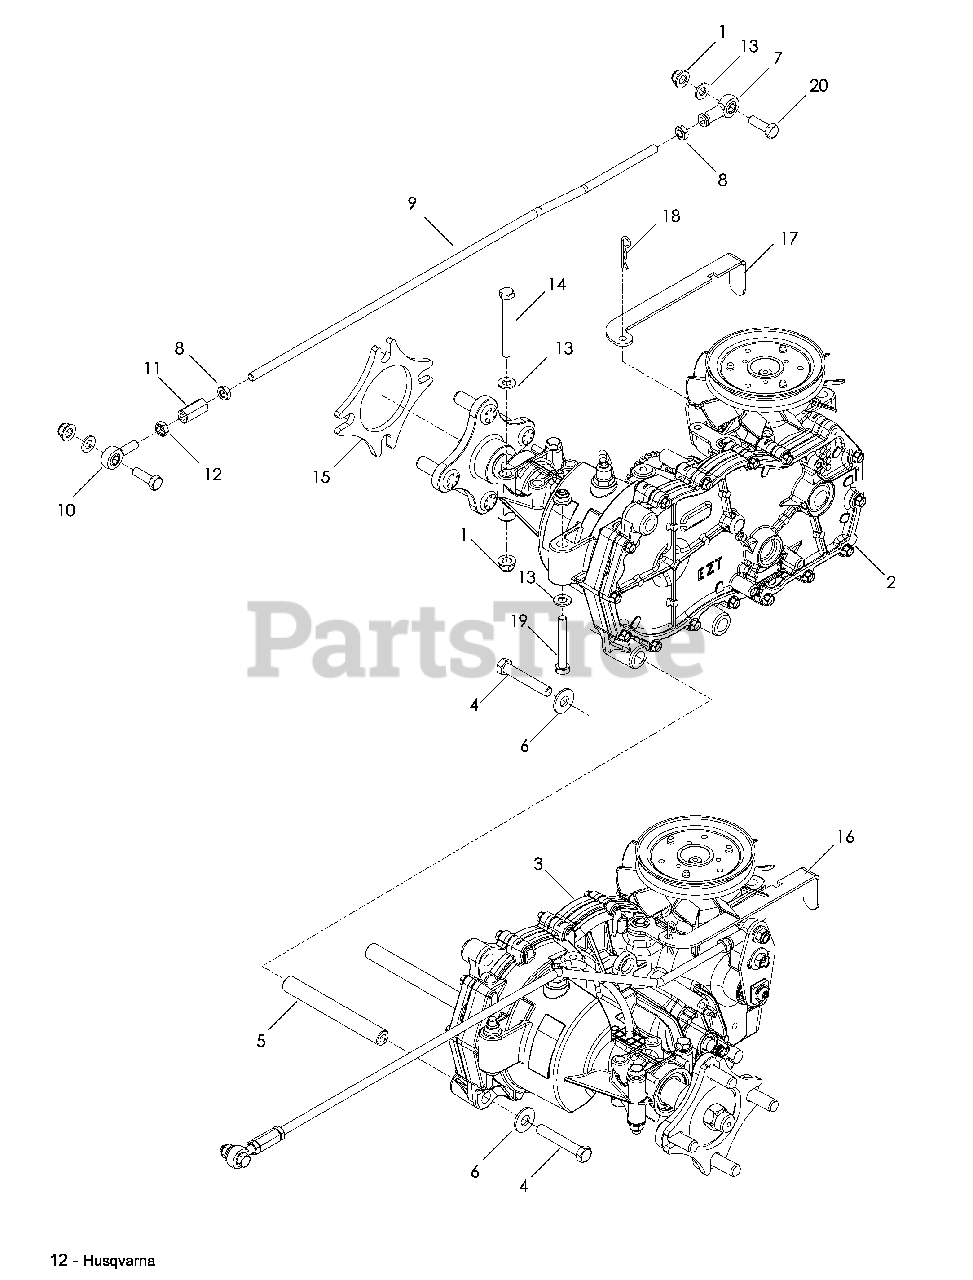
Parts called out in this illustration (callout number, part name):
1	NUT 5/16-18 FLANGE NYLOC
2	HYDRO, RH
4	HCS 3/8-16 x 2¼
5	SPACER, HYDRO
6	WASHER 3/8 FLAT STD
7	ROD END, RH
8	ROD END, MALE LH
9	NUT 5/16-24 HEX JAM
10	ROD, CONTROL
11	ROD END COUPLER
12	NUT 5/16-24 HEX JAM LH
13	WASHER 5/16 SAE FLAT
14	HCS 5/16-18 x 2¾
15	SPACER, WHEEL
16	RELEASE HANDLE, LH
17	RELEASE HANDLE, RH
18	HAIRPIN COTTER
19	HCS 5/16-18 x 2¼
20	HCS 5/16-18 x 1
